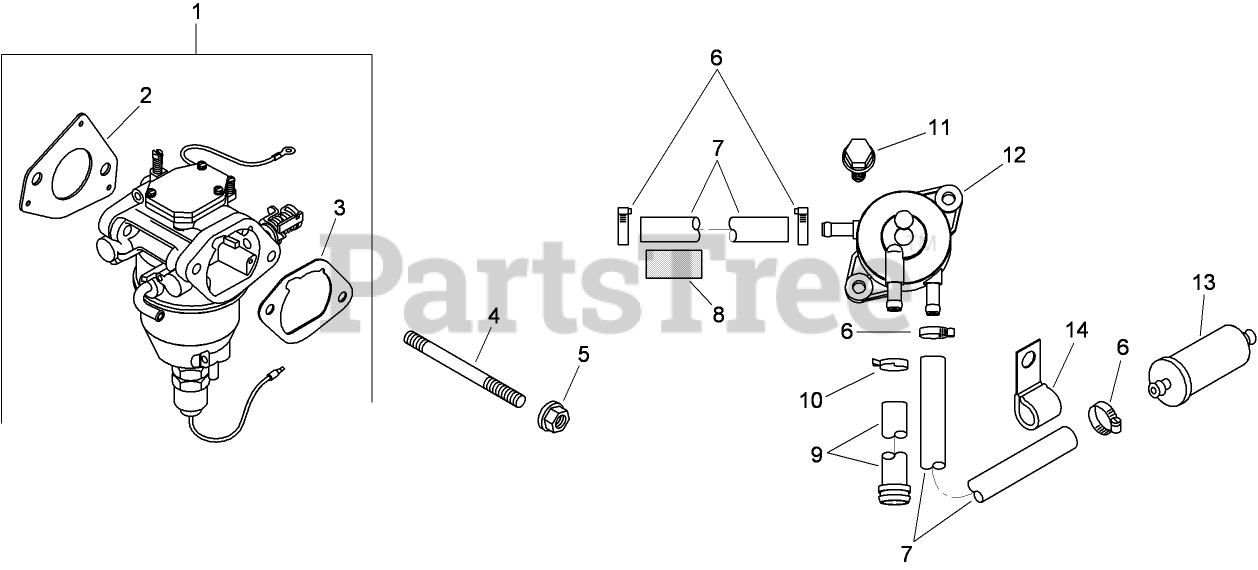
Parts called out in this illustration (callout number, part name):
1	CARBURETOR KIT W/GASKETS (INCLUDES 2-3)
2	GASKET-CARBURETOR
3	GASKET-BASE, AIR CLEANER
4	STUD (M6X1.0X106)
5	NUT-FLANGE (M6X1.0)
6	CLAMP-HOSE, SPRING (1/2)
7	LINE-FUEL (24-CUT TO LENGTH)
8	SLEEVE-ABRASION, ANTI
9	HOSE-FUEL PUMP W/CLAMP (INCLUDES 10)
10	CLAMP-HOSE
11	SCREW-TAP (M6X1.7X18)
12	PUMP-FUEL
13	Filter-Fuel
14	CLIP-CABLE
